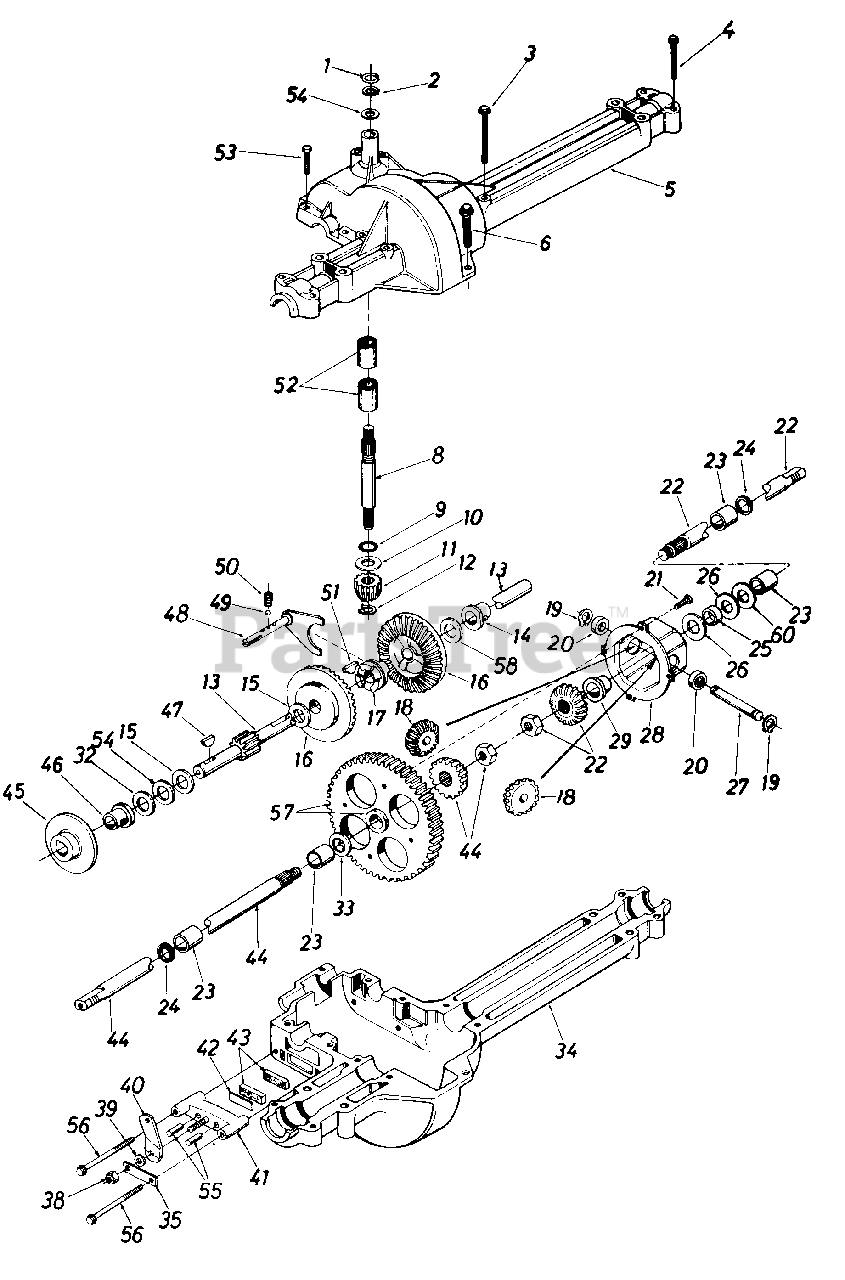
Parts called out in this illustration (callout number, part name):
1	Wire Ring
2	Retaining-Ring
3	Hex Bolt 1/4-20 x 1.75" Lg.
4	Hex Tap Scr. 1/4-20 x 1.25" Lg.
5	Upper Housing
6	Hex TT-Tap Scr. 1/4-20 x .75" Lg.
8	Input Shaft
9	Square Seal 5/8" I.D.
10	Thrust Washer 5/8" I.D. x 1. 25" O.D.
11	Pinion Input 14T
12	Retaining Ring
13	Drive Shaft
14	Flange Brg. 5/8" I.D. x 3/4" Lg.*
15	Fl-Wash. 5/8" I.D. x 1.25"
16	Bevel Gear 42T
17	Clutch Collar
18	Miter Gear 15T (H.D.)
19	Snap Ring
20	Thrust Bearing
21	Pan Head Scr. 1/4-20 x .50" Lg. w/Patch
22	Axle R.H. Ass'y.
23	Sleeve Bearing 3/4" I.D. x 1.0" Lg.
24	Oil Seal 3/4" I.D.
25	Axle Spacer
26	Fl-Wash. .760" I.D. x 1.5" O.D.
27	Cross Shaft
28	Differential Cam Ass'y.
32	Washer
33	Fl-Wash. .760" I.D. x 1.5" O.D.
34	Lower Housing
35	Anti-Rotation Brkt.
38	Hex Nut 5/16-24 Thd.
39	Fl-Wash. .344" I.D. x .875" O.D.
40	Actuating Arm
41	Brake Yoke
42	Puck Plate
43	Brake Puck
44	Axle L.H. Ass'y.
45	Brake Disc
46	Flange Bearing 5/8" I.D. x 15/16" Lg.
47	Woodruff Key 3/16 x 5/8 HT
48	Shift Fork Ass'y.
49	Ball Detent .250" Dia.
50	Spring Detent
51	#9 Hi-Pro Key 3/16" x 3/4" Dia. HT
52	Needle Brg. 5/8" I.D. x 1/2" Lg.
53	Hex Bolt 1/4-20 x 1.00" Lg.
54	Fl-Wash. 5/8" I.D. x 1" O.D. x .020 Thk.
55	Actuating Pin 5/16" Dia.
56	Hex Wash Hd. Self-Tap Scr. 1/4-20 Thd
57	Differential Gear 72T Ass'y. w/ Bearing
58	Fl-Wash. 5/8" I.D. x 1" O.D. x .020 Thk.
60	Washer
